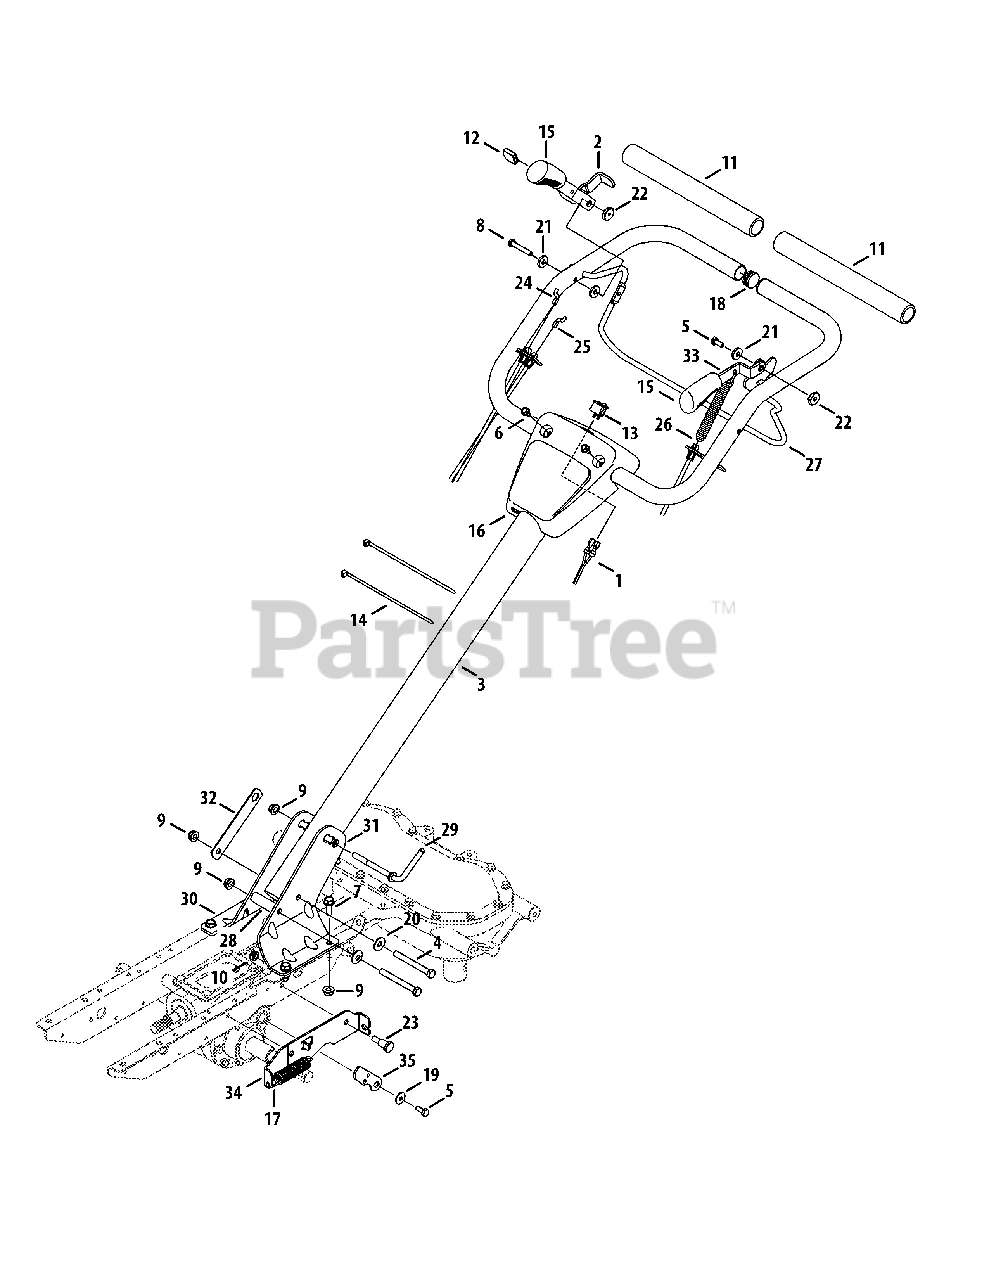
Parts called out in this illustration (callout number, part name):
1	Harness Assembly Adapter
2	Reverse Handle Assembly
3	Handle Assembly
4	Hex Head Screw, 5/16-18 x 3.00
5	Hex Screw, 1/4-20 x .625
6	Screw, 1/4-20 x 0.500
7	Hex Head Washer, 5/16-18 x .875
8	Hex Head Screw, 1/4-20 x 1.62
9	Flangelock Nut, 5/16-18
10	Hex Lock Nut, 5/16-18
11	Foam Handle Grip
12	Reverse Handle Grip
13	Rocker Switch
14	Cable Tie, 8.5 LG
15	Reverse Handle Grip
16	Handle Cover
17	Extension Spring
18	Plug End
19	Bell Washer .265 x 0.75
20	Belleville Washer, .331 x .827 x .098
21	Washer, Flat, .250 x .750 x .119
22	Spacer, .375 x .165
23	Shoulder Screw, .437 Dia. x .54
24	Reverse Cable
25	Forward Cable
26	Neutral Cable
28	Spacer, .322 x .625 x 2.00
29	Handle Crank
30	Handle Bracket, RH
31	Handle Bracket, LH
32	Retainer Nut Bracket
33	Neutral Handle
34	Neutral Cable Frame Bracket
35	Neutral Pivot Lever
